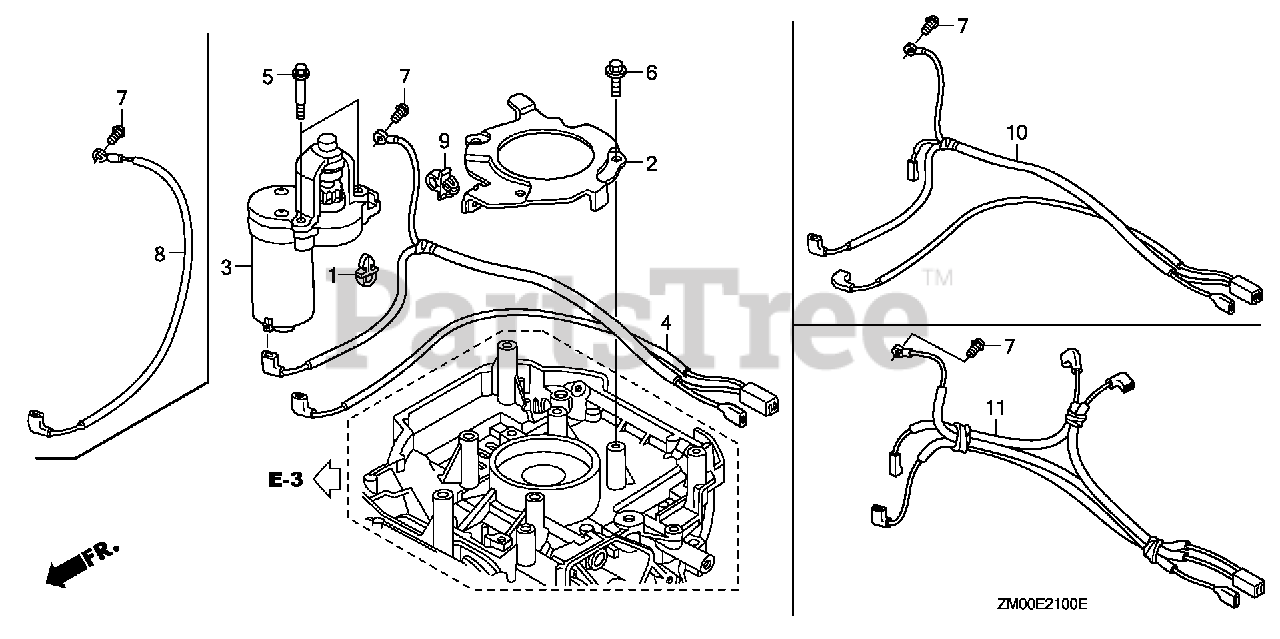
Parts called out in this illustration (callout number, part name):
1	HOLDER, WIRE
2	CLAMP, WIRE
3	STARTER MOTOR ASSY.
4	WIRE, TERMINAL GROUND
5	BOLT, SPECIAL (6MM)
6	BOLT, FLANGE (6X12) (CT200)
7	SCREW, PAN (5X8)
